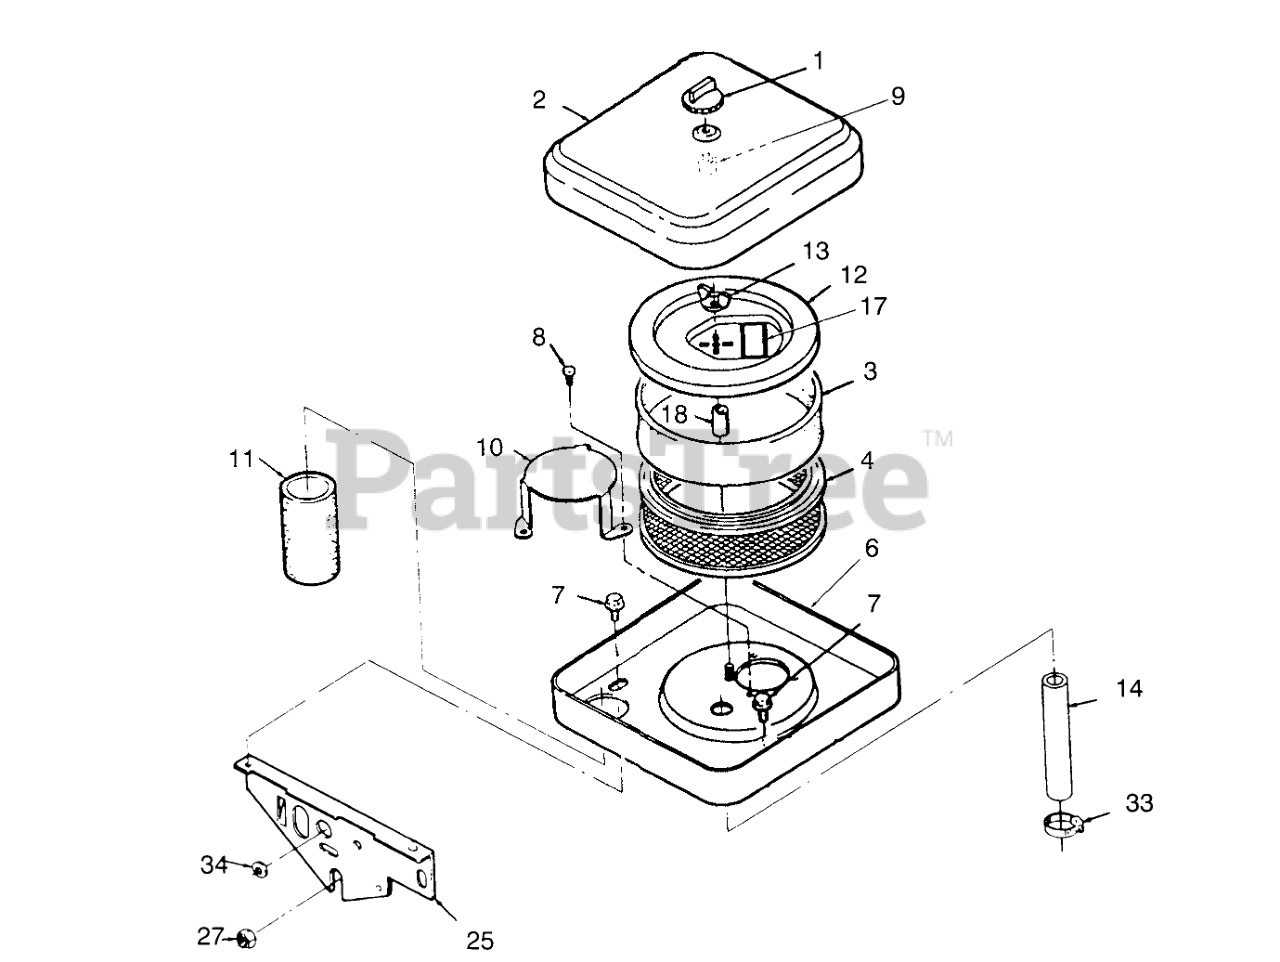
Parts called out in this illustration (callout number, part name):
1	KNOB-TOOL LESS
2	COVER-AIR CLEANER
3	WRAPPER-AIR CLEANER ELEMENT
4	ELEMENT-AIR CLEANER
6	HOUSING-AIR CLEANER
7	SCREW-TAPPING
8	MACHINE SCREW
9	SCREW-TAPPING
10	PLATE-AIR DEFLECTOR
11	TUBE-AIR INTAKE
12	ELEMENT COVER KIT
13	1/4-20 WING NUT
14	HOSE-BREATHER
17	DECAL-PERIODIC MAINTENANCE
18	SPACER-AIR CLEANER STUD
25	SUPPORT-AIR CLEANER
33	CLAMP-HOSE, BREATHER
34	GROMMET
